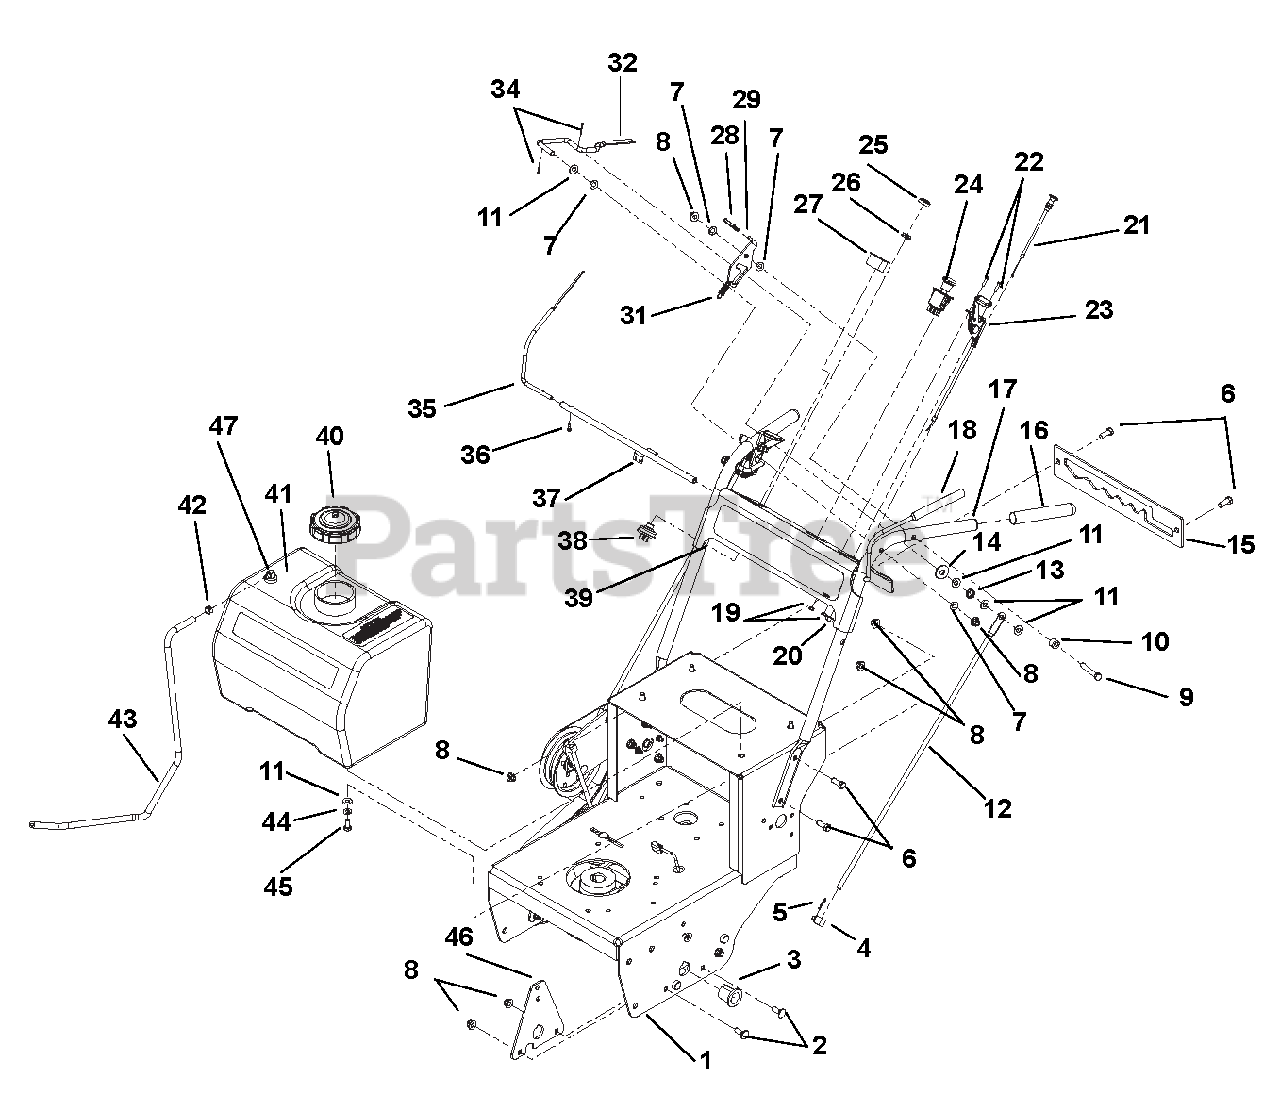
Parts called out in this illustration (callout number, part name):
1	ARIENS GRWLK FRAME W/DECALS
2	BOLT, 3/8-16X1.00 CRG 5 Y
3	BSHG-FLG 1.010X1.38X1.4X1.65
4	SWIVEL, 3/8-24
5	PIN-HAIR, ENDRIES #25 YWZC
6	BOLT, 3/8-16X1.00 HEX 5 Y
7	WSHR-FL-NY .375X.75X.060
8	@NUT-LK-NYL-FLG .38-16 YWZC
9	BOLT, 3/8-16X2.50 HEX 5 Y
10	BSHG-SLV .391X.688X.52 PM
11	WASHER, .406X.813X.065 FLAT Y
12	ROD, STEERING
13	SG-COMP .045X.600X.750 WLD7.5
14	@WSHR-FL-STL.50X1.25X.083 YWZC
15	PLATE, SHIFT LEVER DETENT ARIE
16	GRIP, HANDLEBAR
17	CAPLUG, HANDLEBAR
18	LEVER, LH-OP
19	LOCKNUT, 10-24 NYLOC Y
20	NUT, 3/8-24 STD HEX Y
21	CABLE, CHOKE
22	@SCR-MCH 10-24X.75 HWH YWZC
23	CABLE - THROTTLE W/LINER
24	SWITCH, CLUTCH (WITH GRAPHIC)
25	CAP - IGNITION SWITCH
26	NUT- PANEL .562-24 GRECO
27	METER, HOUR INDCTV RECOIL ENG
28	GRIP, THUMB LATCH
29	LATCH, LH THUMB
30	LATCH, RH THUMB
31	SG-TENS .041X.500X1.750
32	LEVER, HAND CONTROL LH
33	LEVER, HAND CONTROL RH
34	PIN, COT .094X.750 EXTP Y
35	LEVER, RH-OP
36	@SCR-TAP 8-32X.50 HWH TR YWZC
37	WELDMENT, PIVOT TUBE
38	KEY SWITCH
39	ARIENS GRWLK HANDLEBAR W/DECAL
40	CAP, FUEL NONVENT, AUTOLOCK
41	ASSY, FUEL TANK FF CLPE WALK
42	CLAMP, FUEL LINE
43	HOSE, FUEL 1/4 X 18.00
44	WASHER, .375 MED SPRG LOCK Y
45	BOLT, 3/8-16X.750 HEX 5 Y
46	PLATE, AXLE/BEARING MOUNTING
47	FITTING, TANK
